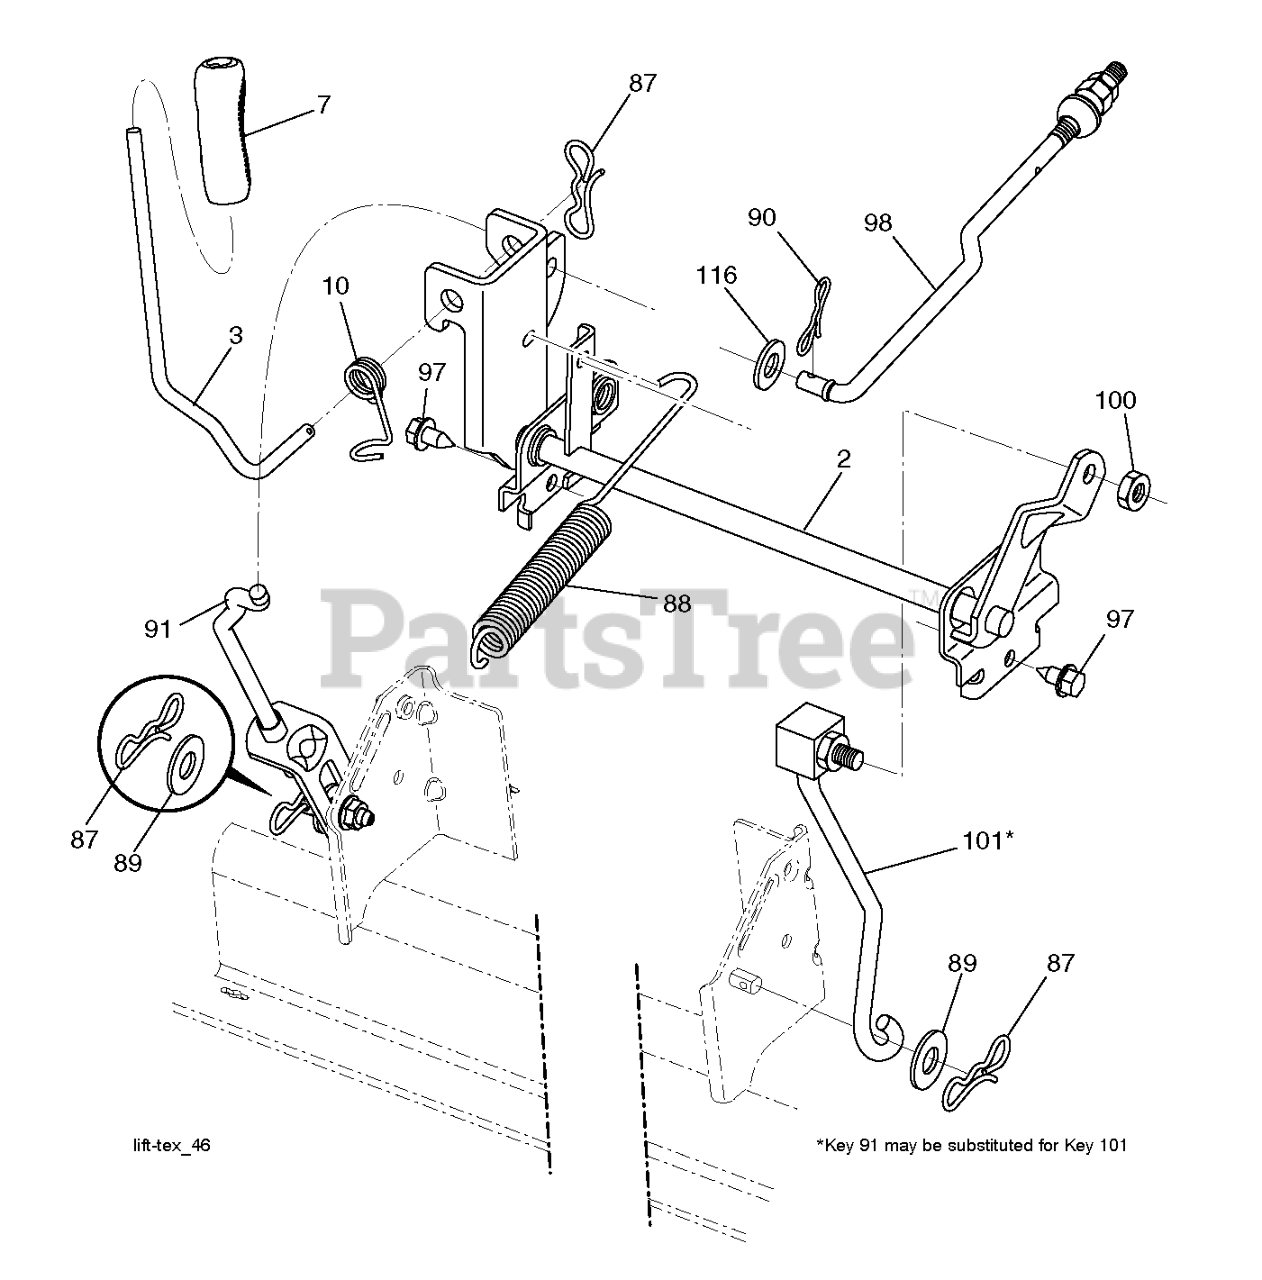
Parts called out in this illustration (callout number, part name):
2	SHAFT.ASM.CROSS.LIFT
3	LEVER.LIFT.HANDLE.LT
7	GRIP.HANDLE.LIFT.PVC.BLACK
10	SPRING.TORSION.LIFT.HANDLE
87	PIN.COTTER.7/16.BOW TI.
88	SPRING.LIFT.ASSIST
89	WASHER.CLEAR.ZINC
90	PIN.COTTER.5/16.BOW TI
91	LINK ASSY LIFT.REAR 10.951 BLA
97	SCREW, 3/8-16X3/4
98	LINK.FRONT.MOWER.SUSP.ASM.BLK
100	Nut, Hex, Centerlock 3/8-16 UNC (AYP part number)
101	LINK.ASSY.BLACK.431
116	Washer 15/32 x 15/16 x 16 Gauge (AYP part number)
